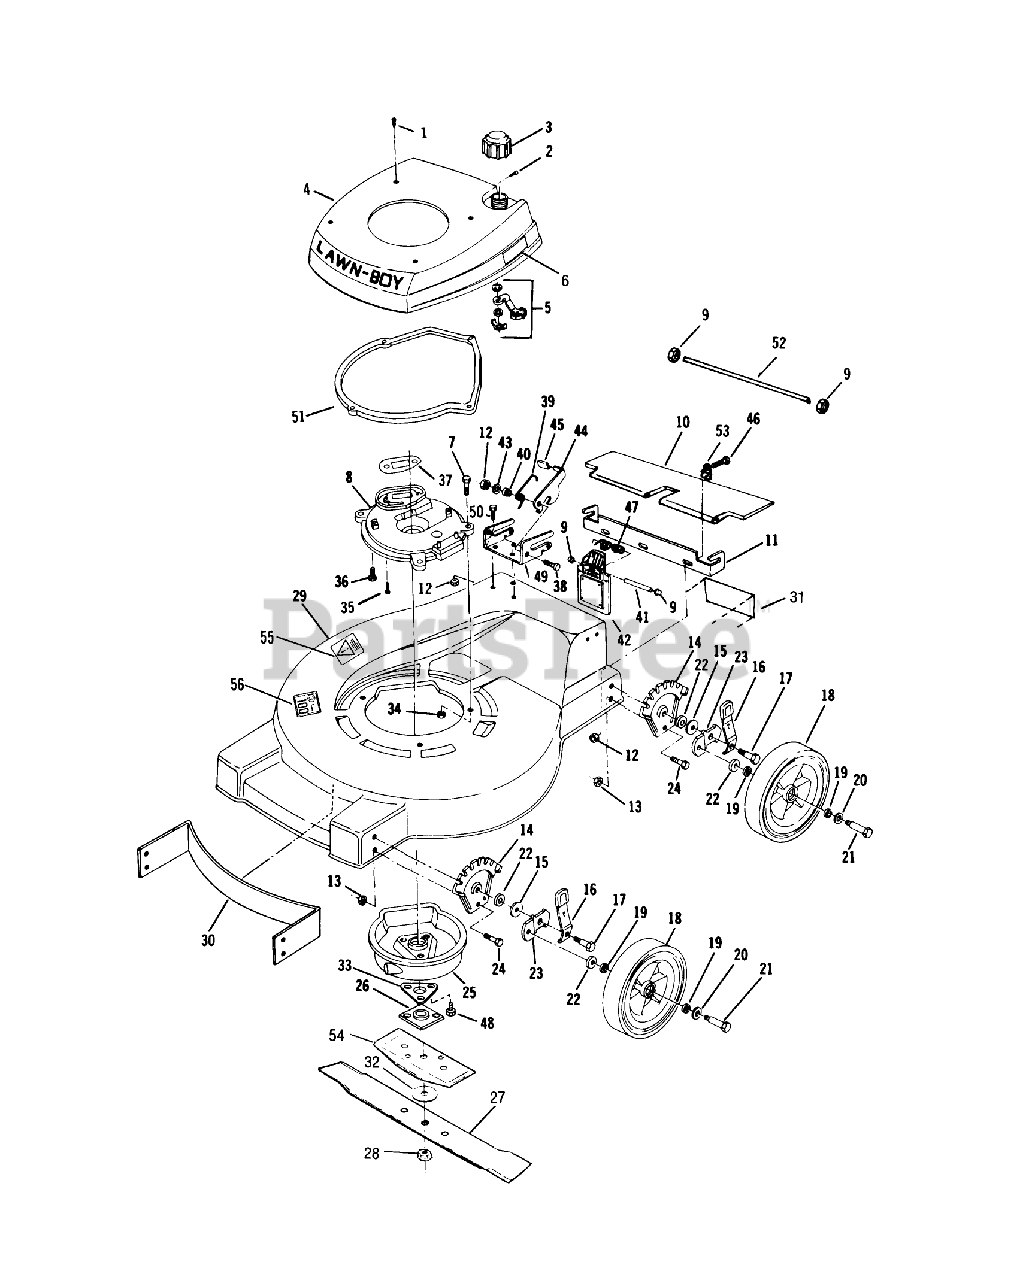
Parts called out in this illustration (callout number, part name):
1	SCREW LAWRENCE
2	SCREW S
3	FUEL CAP & INSERT
7	SCREW-HH
8	PLATE,MUFFLER F
10	T/SHIELD SM&P
12	LOCKNUT E
13	LOCKNUT
15	WASHER
16	KNOB&SPRING FORMCO
17	BOLT
19	WASHER
20	SPACER
21	BOLT WHEEL
22	WASHER WROUGHT
26	PLATE AND COLLAR ASM
27	BLADE EURO WHIRL
28	NUT-BLADE
32	WASHER
33	SUPPORT F
34	NUT-LOCK F
35	SCREW V
39	SPRING
41	ROD ROCK/HDWE
45	KNOB (S&R)
47	SPRING ASOC
48	SCREW
